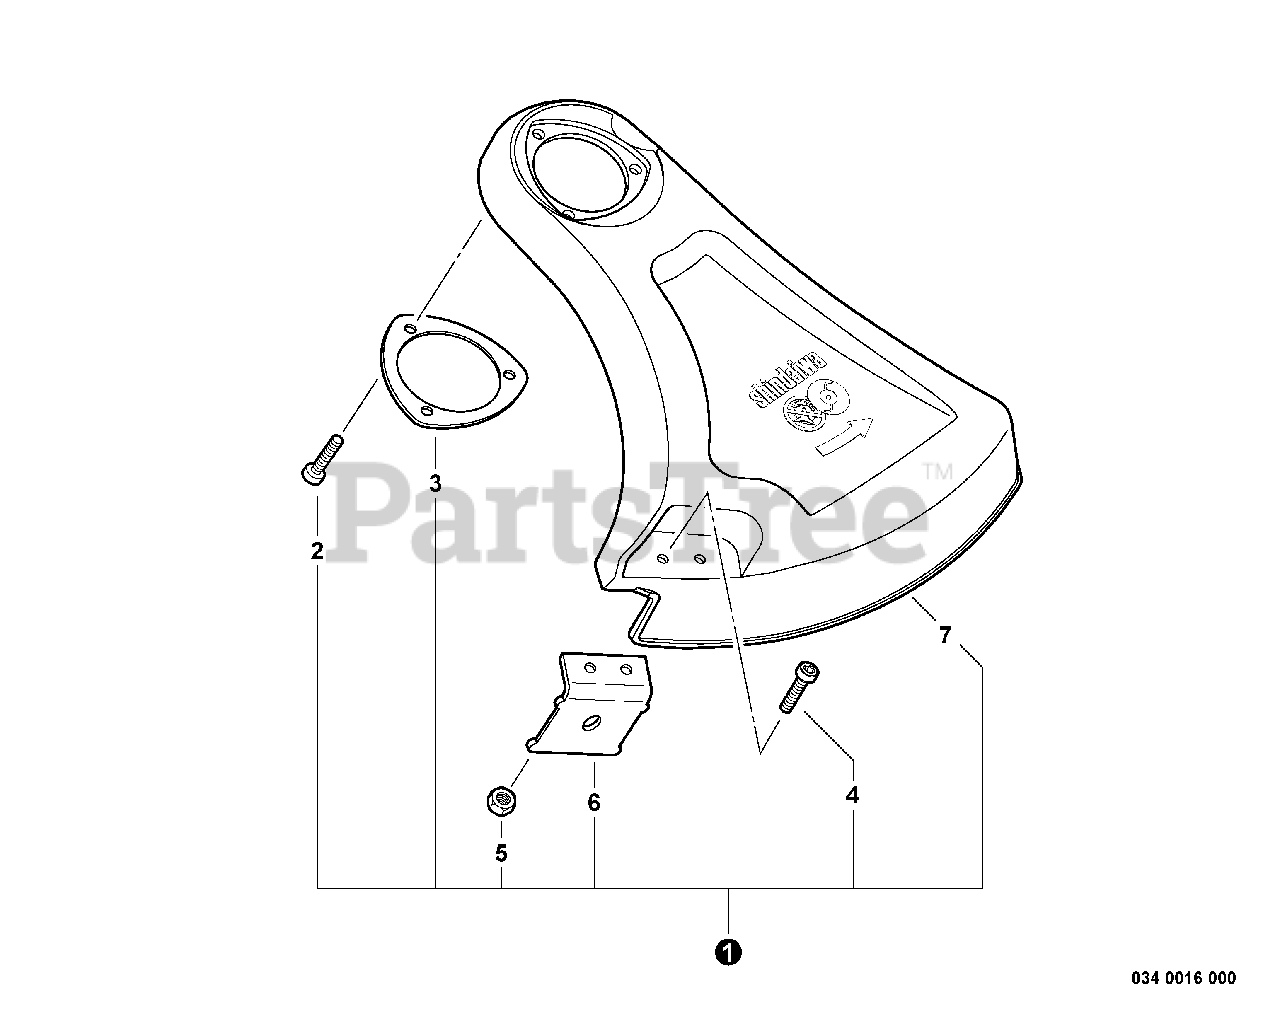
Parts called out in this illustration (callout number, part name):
1	DEBRIS SHIELD ASSY
2	BOLT, TORX 5×16
3	PLATE, SHIELD Ø49.5 MM
4	BOLT, TORX 5×12
5	NUT M5
6	CUTTER, LINE
7	SHIELD, DEBRIS
